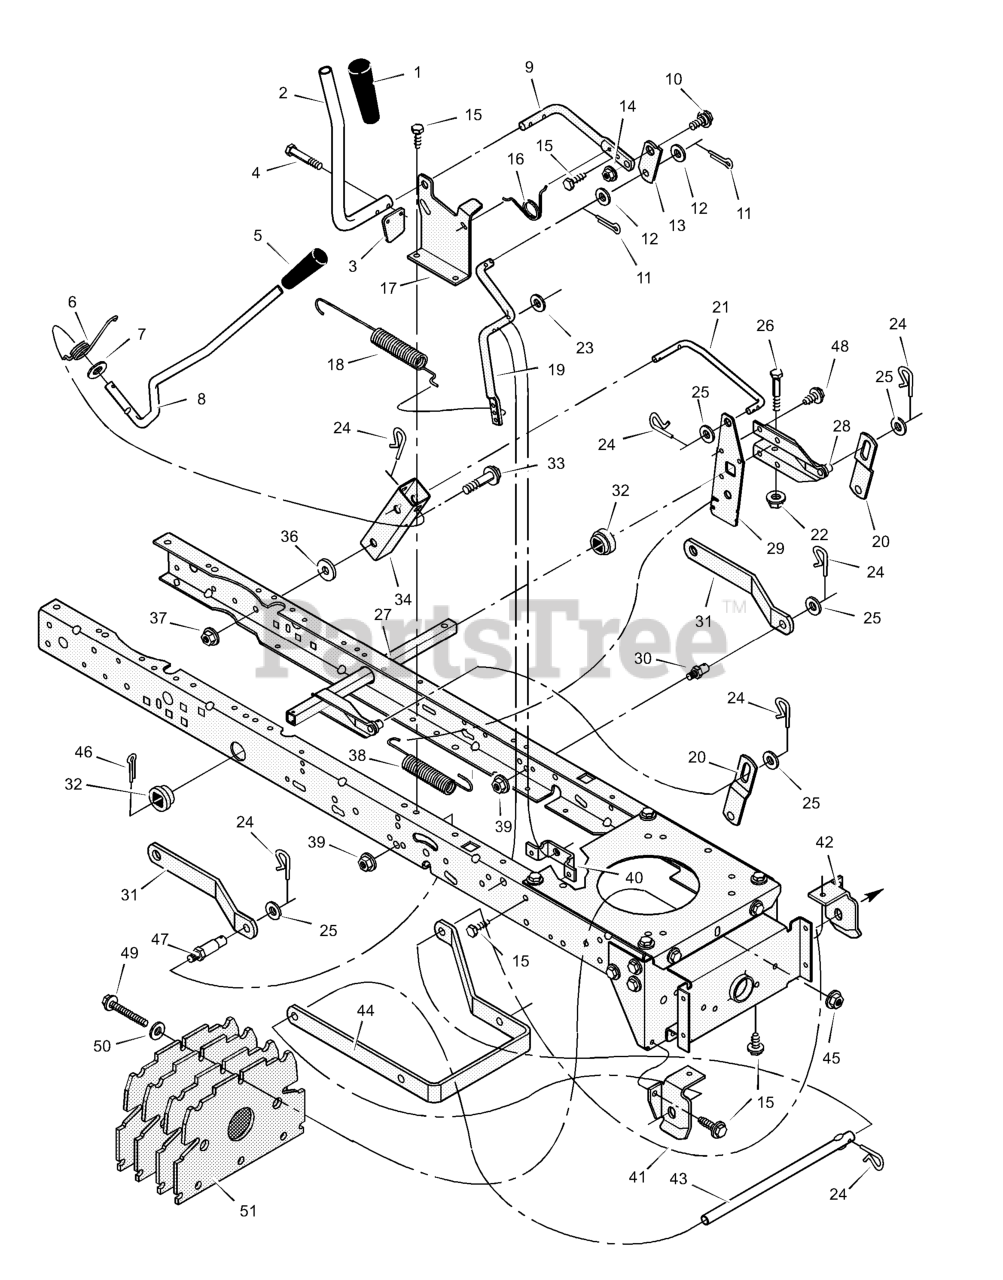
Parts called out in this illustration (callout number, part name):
1	Grip
2	Handle, PTO
3	Pad, Switch
4	Screw, Hex
5	Grip
8	Handle, Lift
9	Lever, PTO
10	Bolt, Shoulder
11	Pin, Cotter
13	Link, PTO
14	Nut, Flange
17	Bracket, PTO
19	Crank, PTO
20	Link, Lift
21	Link, Lift Handle
22	Nut, Flange
24	Pin, Hair
26	Bolt, Hex
27	Arm Assembly, Right Lift
28	Arm, Right Lift
29	Plate, Lift Arm
30	Pin
31	Bracket, Rear Suspension
32	Bushing, Lift Tube
33	Bolt, Shoulder
34	Bracket, Pivot
37	Nut, Flange
39	Nut, Flange
40	Bracket, PTO
41	Hanger, Right Deck
42	Hanger, Left Deck
43	Rod, Hanger
44	Hanger, Front
45	Nut, Flange
46	Pin, Cotter
47	Pin, Threaded Shoulder
49	Bolt, Hex
51	Plate, Weight (4 Required)
